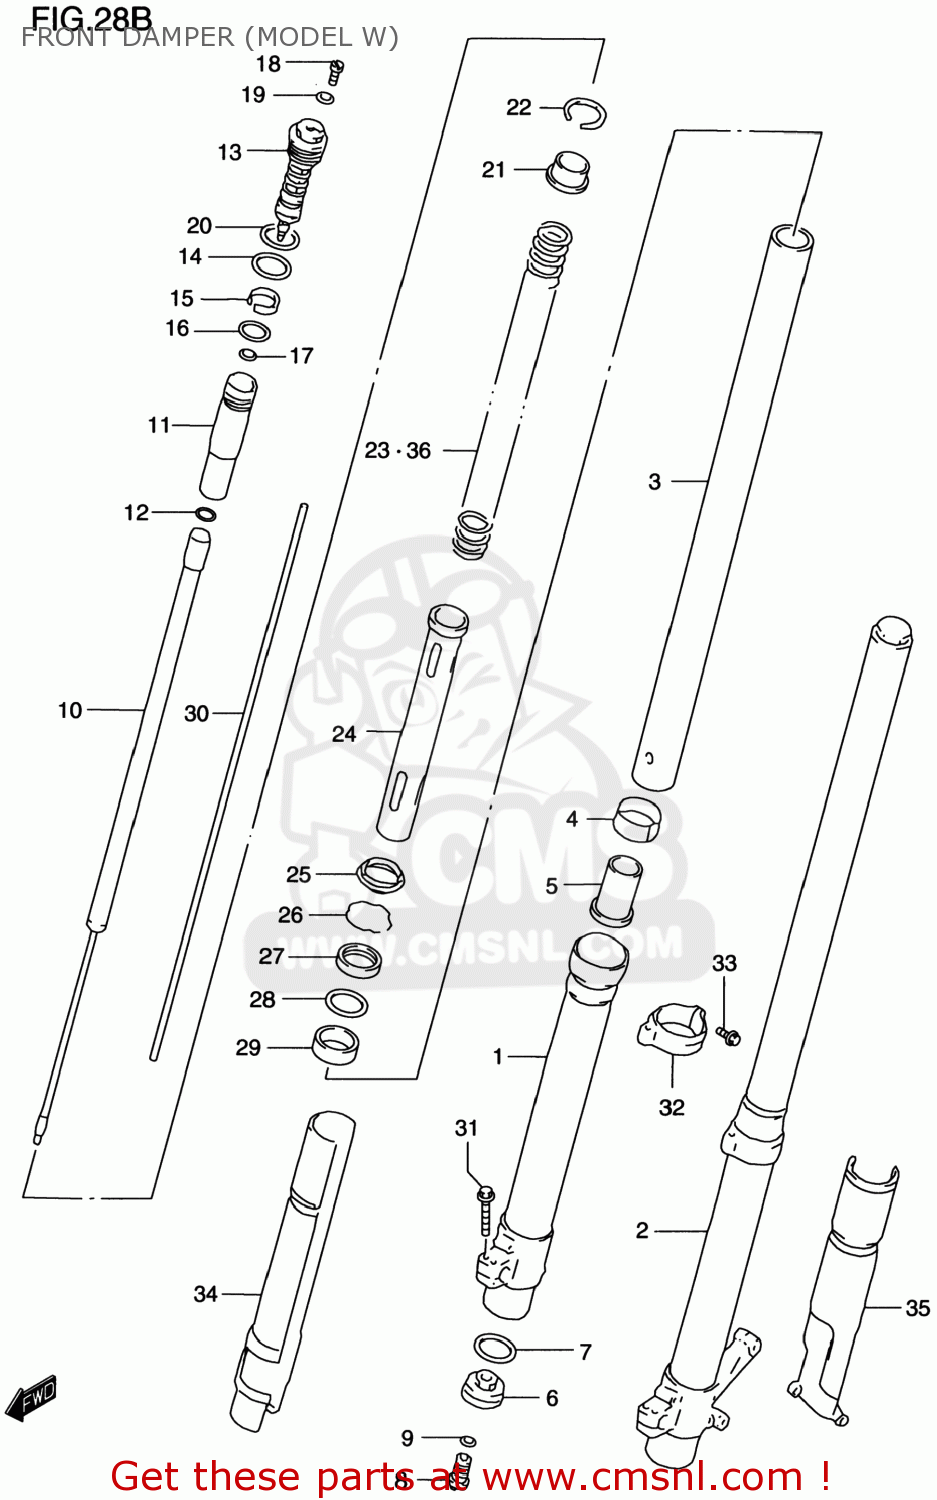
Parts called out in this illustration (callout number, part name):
1	TUBE,OUTER,R
2	TUBE,OUTER,LEFT
3	TUBE,INNER
4	BUSH,SLIDE
5	PIECE,OIL LOCK
6	PLATE,END
7	O RING
8	BOLT,CTR
9	O RING,CTR BOLT
10	ROD,FR DAMPER
11	TANK,SUB
12	O-RING
13	BOLT,FORK
14	O RING
15	BUSHING,SLIDE
16	O RING
17	O RING
18	BOLT,PLUG
19	O RING,PLUG
20	O RING
21	SPRING,STOPPER
22	RING,STOPPER
23	SPRING,FRONT (K=0.42)
24	COLLAR,SPRING
25	SEAL,DUST
26	RING,STOPPER
27	SEAL,OIL
28	SPACER,SEAL
29	BUSH,GUIDE
30	ROD,PUSH
31	BOLT,HANDLE HOLDER(8X35)
32	GUIDE,FR PROTECTOR,R
33	BOLT
34	PROTECTOR,OUTER TUBE,R
35	PROTECTOR,OUTER TUBE,L
36	SPRING,FRONT (K=0.40)
